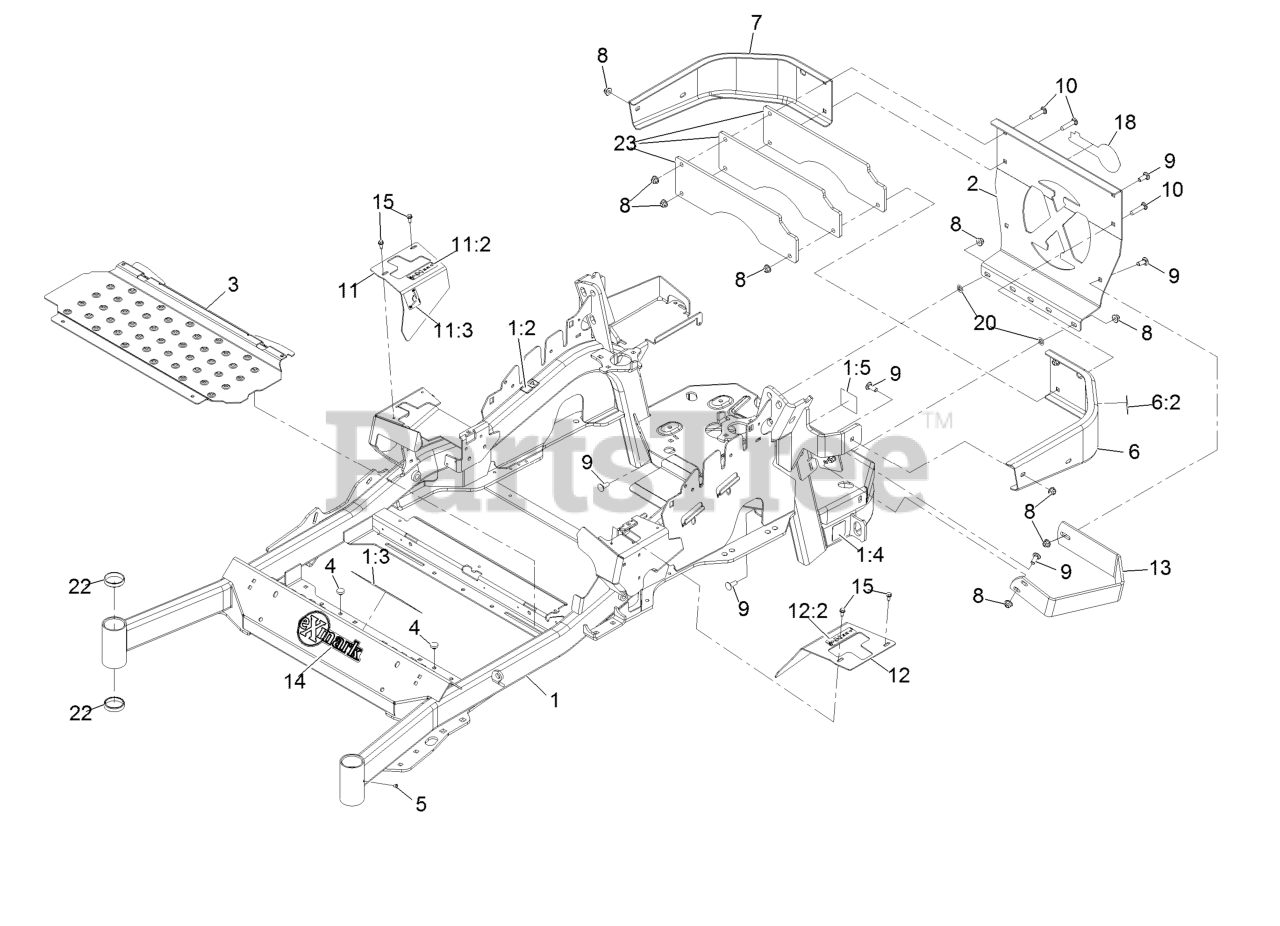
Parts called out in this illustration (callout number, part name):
1	Mainframe ASM
1:2	Decal-Warning
1:3	Decal-Danger
1:4	Decal-Hazard, Pinched Finger
1:5	Decal-Spark Arrester
2	Plate,Rear Guard
6	LH Bumper ASM
6:2	Decal-Warning
7	Bumper-RH
8	Nut-Nyloc 3/8-16 Flg
9	Bolt-Carriage 3/8-16 X 1
10	Bolt-Carriage 3/8-16 X 1 3/4
11	RH Motion Control Cover ASM
11:2	Decal-Control, Motion
11:3	Decal-Park Brake, CE
12	LH Motion Control Cover ASM
12:2	Decal-Control, Motion
13	Guard-Muffler
14	Decal-Exmark
15	Screw-HWH 1/4-20 X .62
18	Decal-Exmark Logo
20	Nut-Push 3/8-16
22	Cup-Bearing Tapered Roller
23	Plate-Weight, 6 Lb
